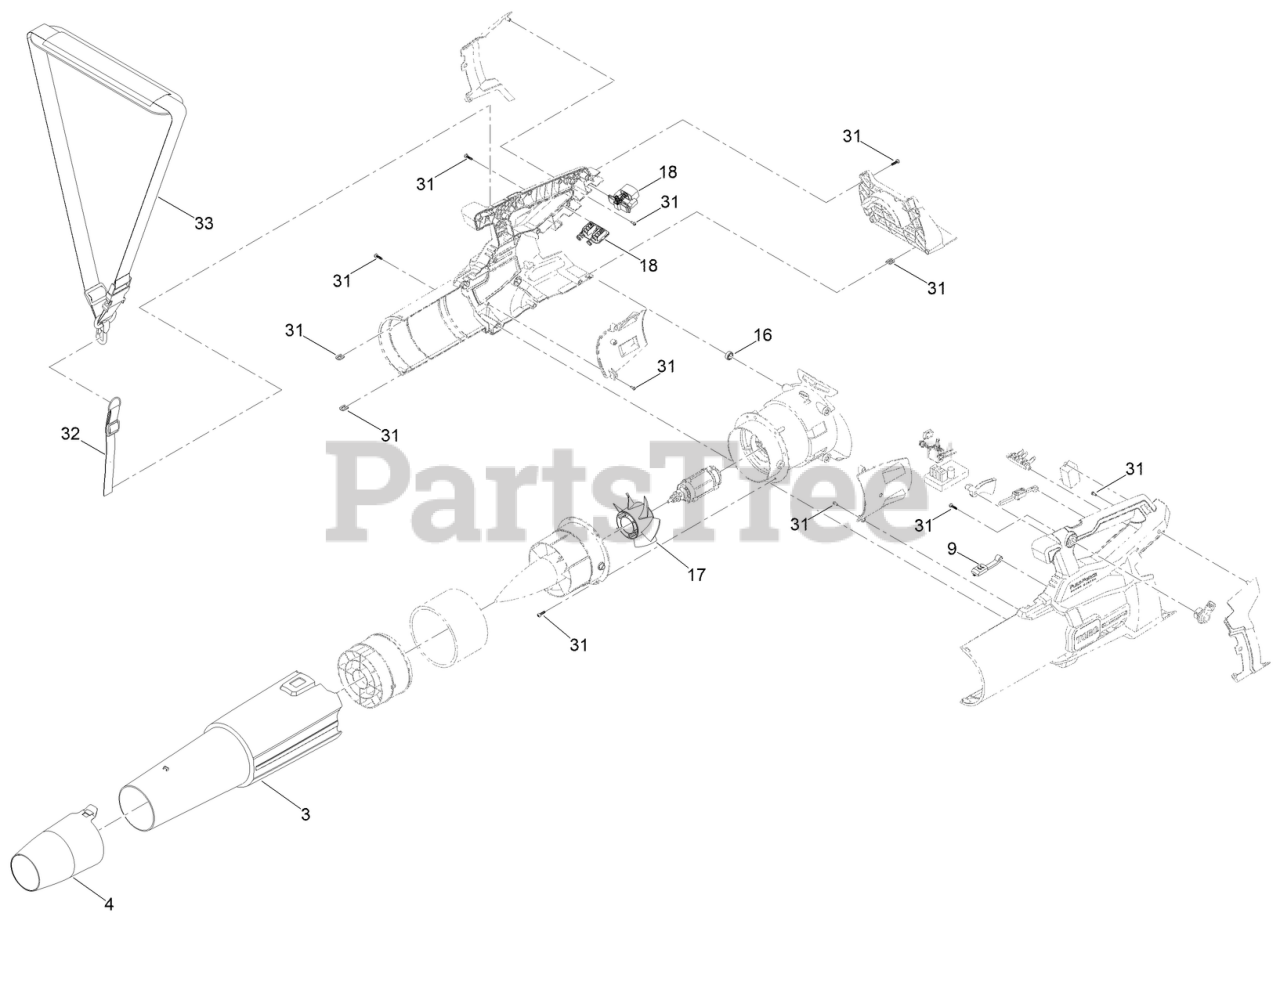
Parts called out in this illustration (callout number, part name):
3	60V AXIAL BLOWER BLOW TUBE
4	60V AXIAL BLOWER REDUCER NOZZLE
9	BLOWTUBE RELEASE SERVICE KIT
16	60V AXIAL BLOWER ISOLATOR KIT
17	60V BLOWER FAN SERVICE ASM
18	60V AXIAL BLOWER BATTERY LATCH
31	60V AXIAL BLOWER HARDWARE KIT
32	60V BLOWER STRAP
33	SHOULDER STRAP
